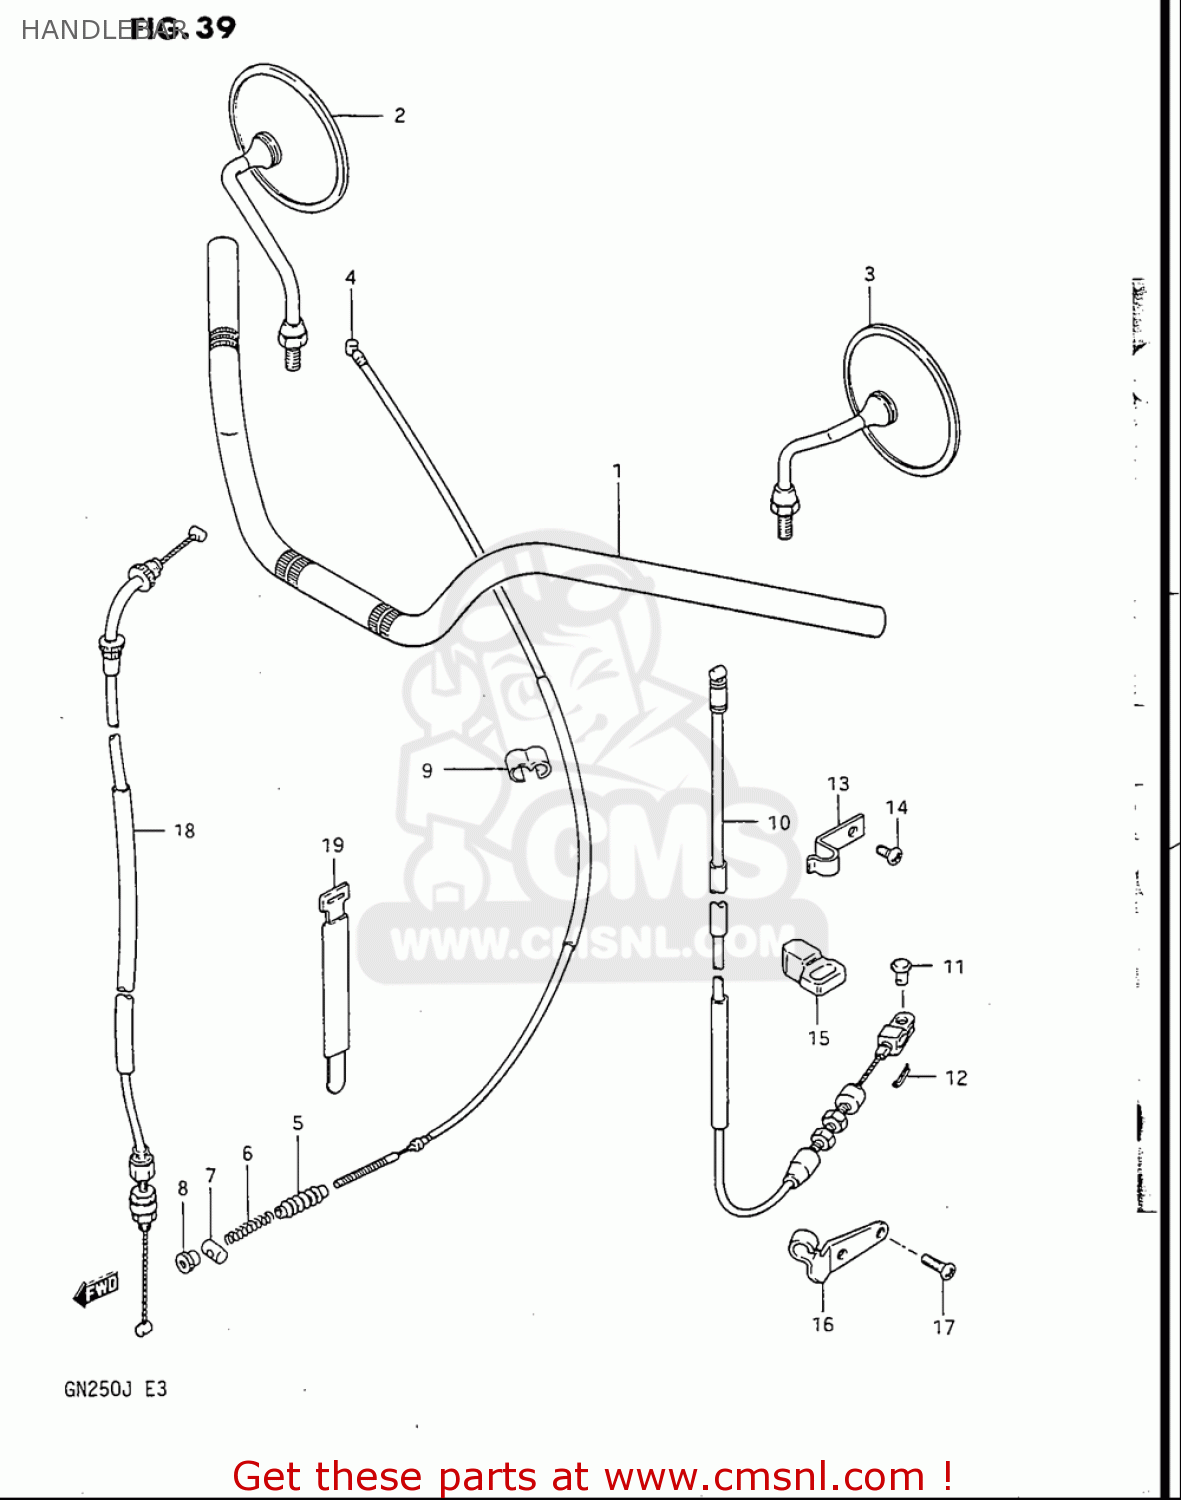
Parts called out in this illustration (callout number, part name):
1	HANDLEBAR
2	MIRROR ASSY,RR VIEW,R
3	MIRROR ASSY,RR VIEW,L
4	CABLE ASSEMBLY,FRONT BRAKE
7	PIN(13X18)
8	NUT
9	CLIP
10	CABLE ASSY,CLUTCH
11	PIN(L:13)
12	PIN
14	SCREW
15	GUIDE,CLUTCH CABLE
16	STOPPER,CLUTCH CABLE
17	SCREW
18	CABLE ASSY,THROTTLE
19	CLAMP(L:250)
